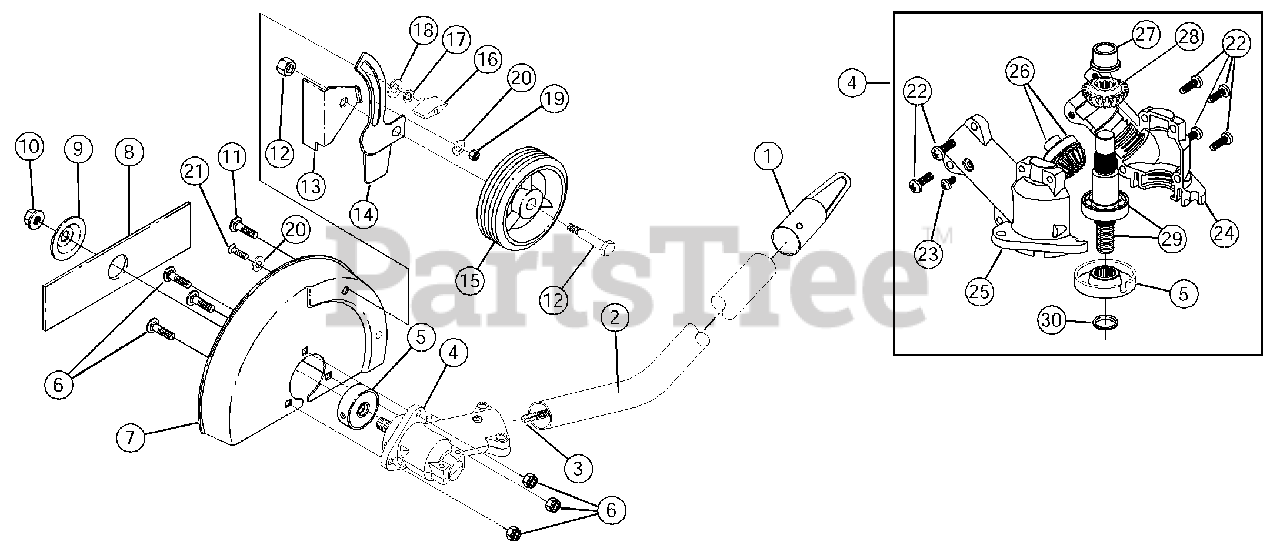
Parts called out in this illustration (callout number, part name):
1	Hanger
2	Drive Shaft Housing Assembly
3	Drive Shaft Assembly
4	Gearbox Assembly
5	Blade Driver
6	Shield Mount Screw Assembly
7	Blade Shield
8	Edger Blade
9	Retaining Washer
10	Lock Nut
11	Shoulder Bolt
12	Wheel Mounting Hardware
13	Deflector
14	Guide Bracket
16	Adjustment Knob
17	Lock Washer
19	Locknut
22	Gearbox Mounting Hardware
23	Anti-Rotation Screw
24	Left Housing
25	Right Housing
26	Pinion Gear Assembly
27	Output Shaft Bushing
28	Output Shaft Gear
29	Output Shaft Assembly
30	Palnut
